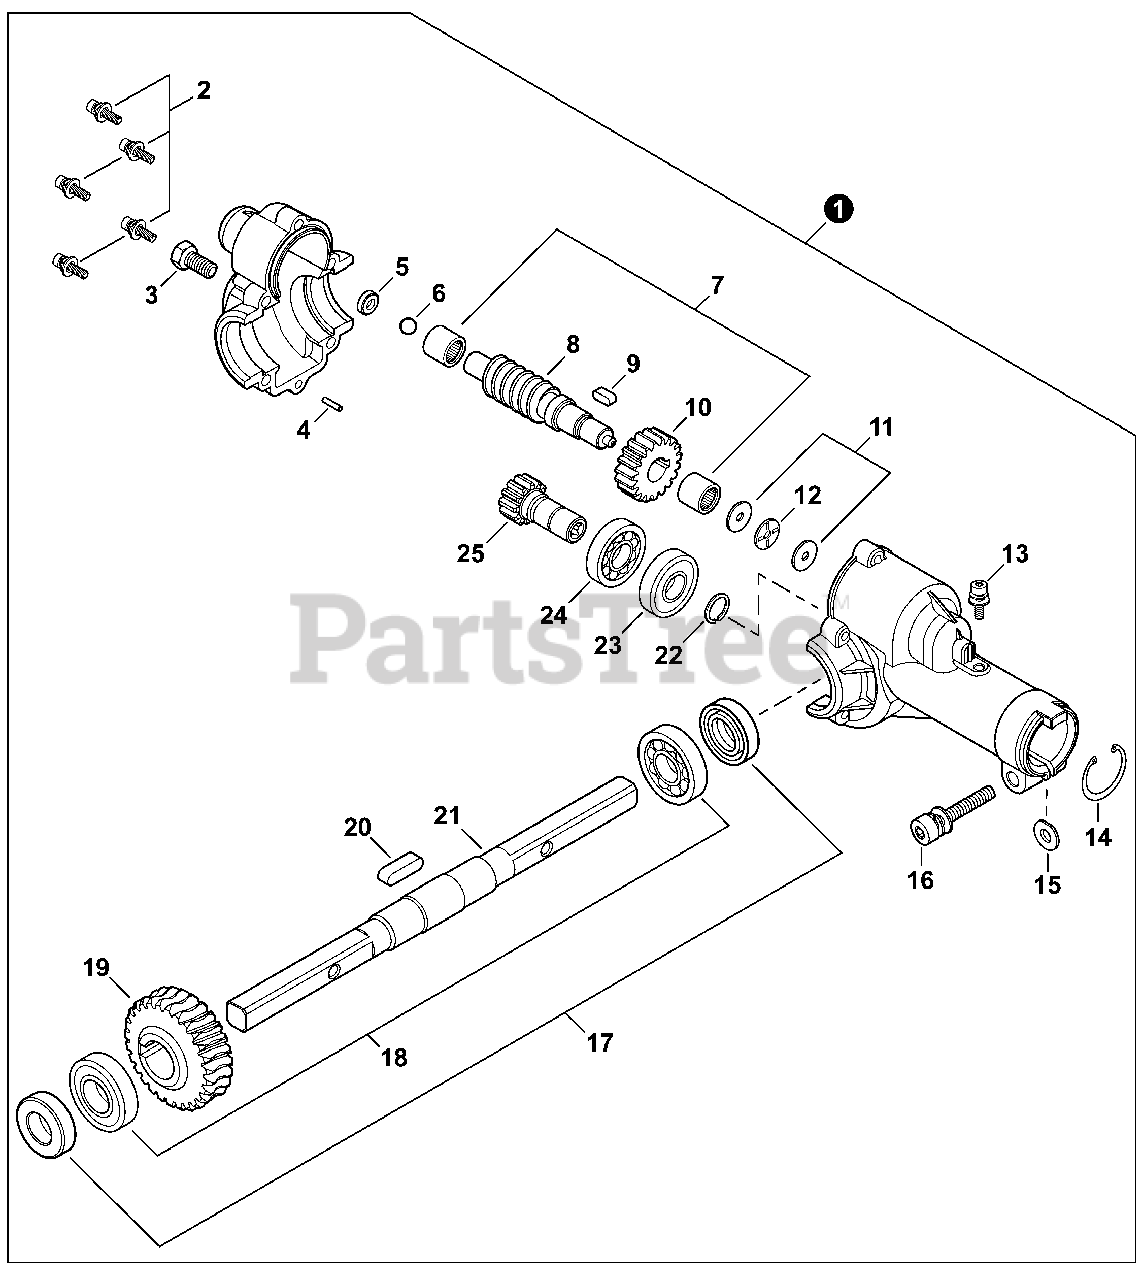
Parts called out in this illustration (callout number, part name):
1	GEAR CASE ASSY
2	BOLT 5×20
3	BOLT 8×10
4	PIN, LOCATING 4×20
7	BEARING, NEEDLE 10
8	GEAR, WORM
9	KEY, WOODRUFF
10	GEAR, SPUR 19 TOOTH
12	BEARING, THRUST
13	BOLT 5×12
14	RING, RETAINING Ø24
15	D-WASHER
16	BOLT 6×30
17	SEAL, OIL 17
18	BEARING, BALL 6003
19	GEAR, WORM WHEEL
20	KEY, WOODRUFF
21	SHAFT, WORM WHEEL
22	RING, SNAP Ø12
23	BEARING, BALL 6901
24	BEARING, BALL 6901
25	GEAR, SPUR 12 TOOTH
